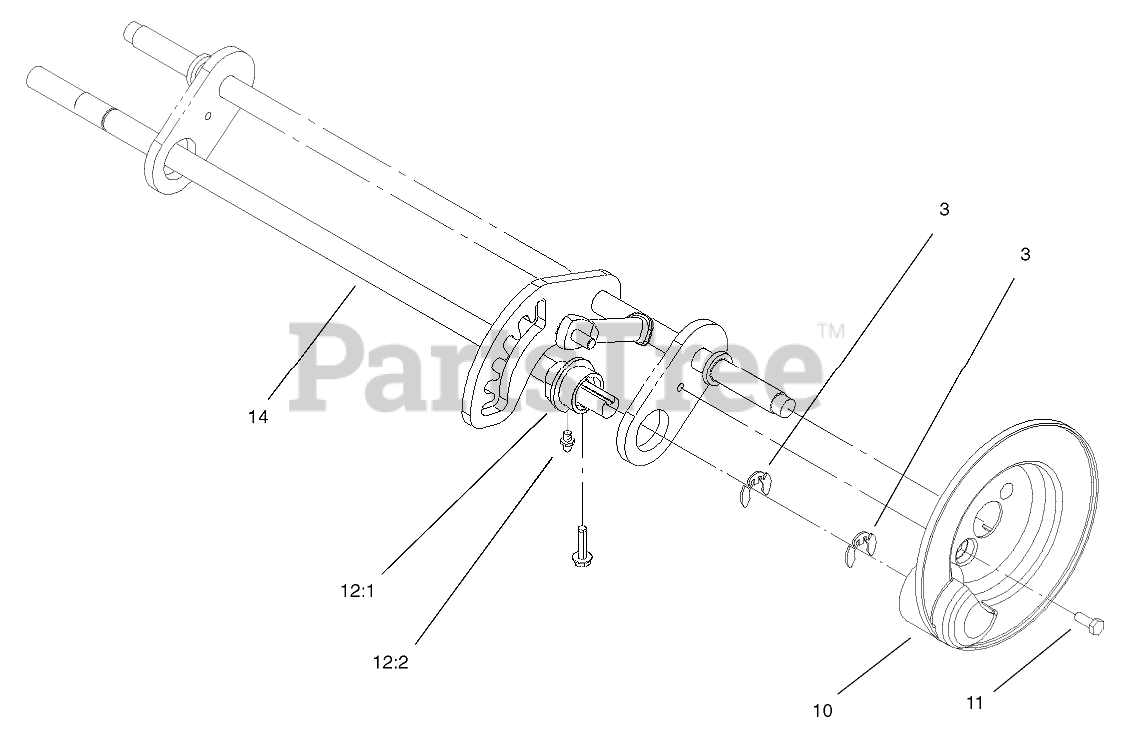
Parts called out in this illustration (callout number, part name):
3	RING-CLIP, LOCKING
10	COVER-GEAR
11	SCREW-TAPTITE
12	BUSHING ASM
12:1	BUSHING
12:2	FITTING-GREASE
14	SHAFT-PIVOT
